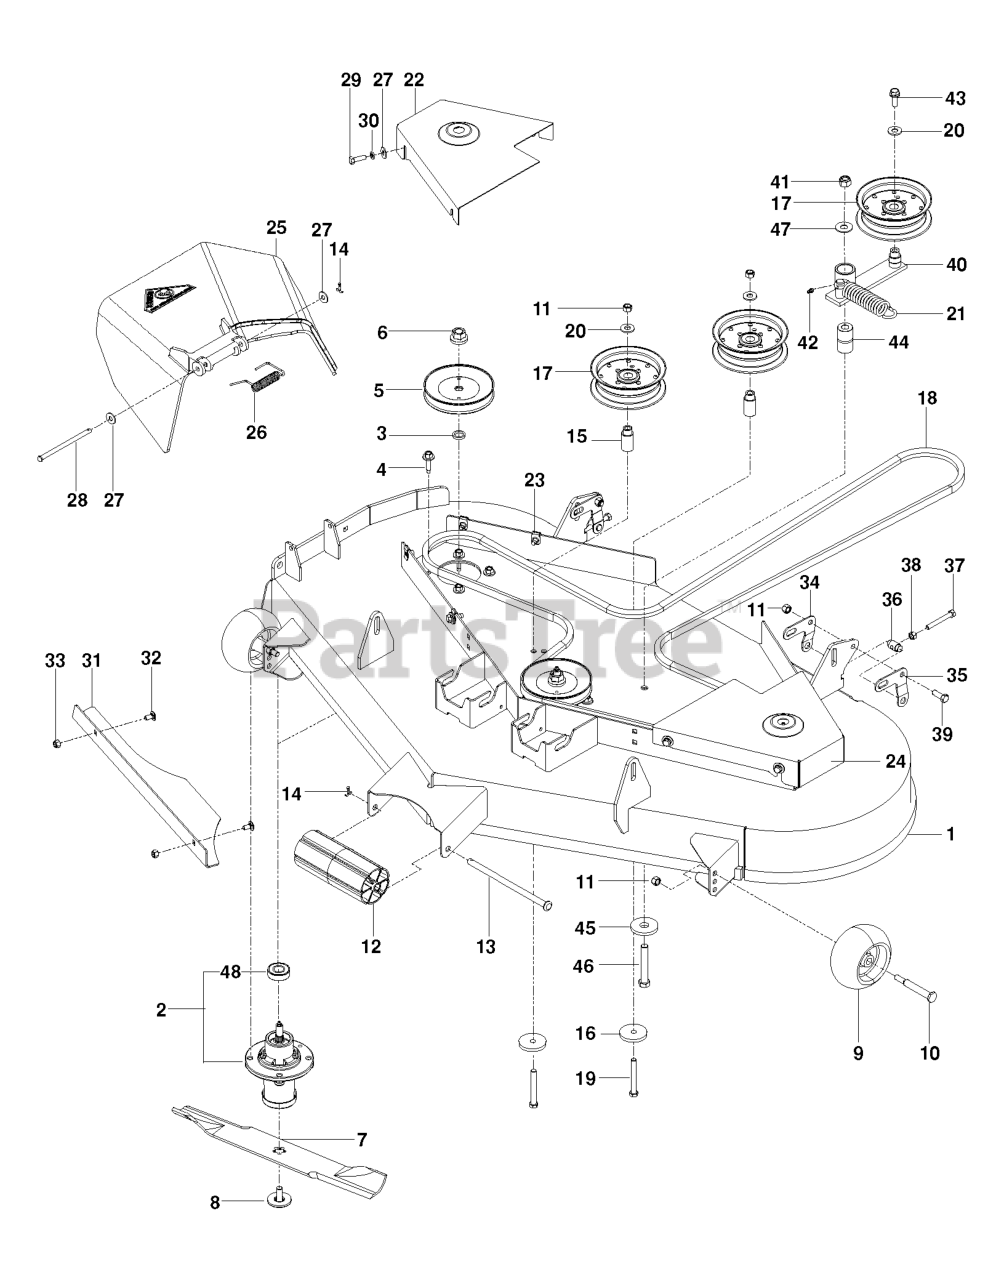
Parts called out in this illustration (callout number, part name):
1	DECK.FAB.W/DECALS.52".MZ.ORANG
2	MANDREL.DECK.ASSEMBLY
3	WASHER-SPACER
4	WASHER HEAD SCREW
5	PULLEY
6	LOCKNUT - 9/16
7	BLADE, 18"
8	BLADE BOLT ASSY-7/16" TB REPL
9	GAUGE WHEEL
10	SHOULDER BOLT 1/2X2-5/8 ZD SPE
11	NUT 3/8-16 NYLOC
12	NOSE ROLLER 48"
13	NOSE ROLLER ROD
14	RP_COTTER PIN 1/8 X 3/4
15	IDLER BUSHING
16	SPINDLE WASHER
17	PULLEY, IDLER
18	BELT.DECK.52".54"
19	HCS 3/8C X 3
20	WASHER 3/8 FLAT
22	BELT SHIELD, RIGHT 52, ORG
23	U-CLIP 5/16-18 NUT RETAINER
24	BELT SHIELD, LEFT 52, ORG
25	DISCHARGE CHUTE 52"
26	SPRING - TORSION
27	WASHER 5/16 FLAT
28	PIN-CLEVIS 5/16 DIA X 5.19 ZD
29	HCS 5/16C X 1
30	WASHER.LOCK.HVY.HLCL.SPR.5/16
31	CONFINEMENT PLATE, 52"
32	CARRIAGE BOLT 5/16C X 5/8"
33	NUT 5/16 NYLOC
34	PITCH, ADJUST, RT
35	PITCH, ADJUST, LT
36	TRUNION, PITCH
37	HCS 5/16-18 X 2 1/2 TPBLT
38	NUT 5/16C HEX
39	HCS 3/8-16X1.GRD.5.ZD
41	NUT 1/2-13 HEX NYLOC ZD
42	ZERK
43	4CS 3/8C X 1 SERRATED HEAD
44	PIVOT BUSHING
45	WASHER, SUPPORT
46	HCS 1/2C X 3 1/4
47	WASHER 1/2 FLAT
48	BEARING, BALL
